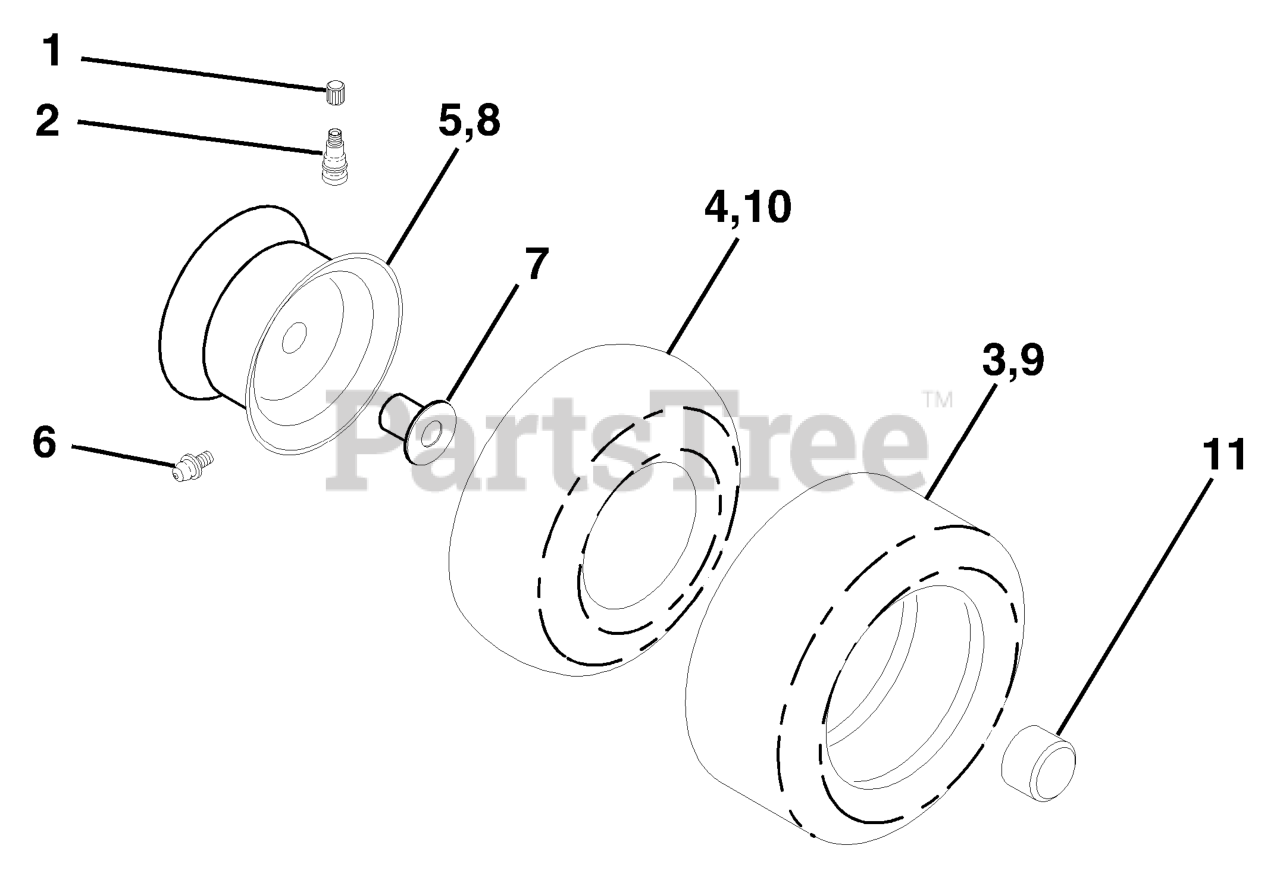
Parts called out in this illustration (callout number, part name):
2	VALVE STEM LT
3	TIRE HEAVY DUTY
4	TUBE.5.3/4.5/6
5	RIM ASM 6" FRONT SILVER
6	FITTING LT
7	BEARING T
8	RIM ASM 8" REAR SILVER
9	TIRE
10	TUBE
11	CAP.HUB.FRONT.LT.BLACK
